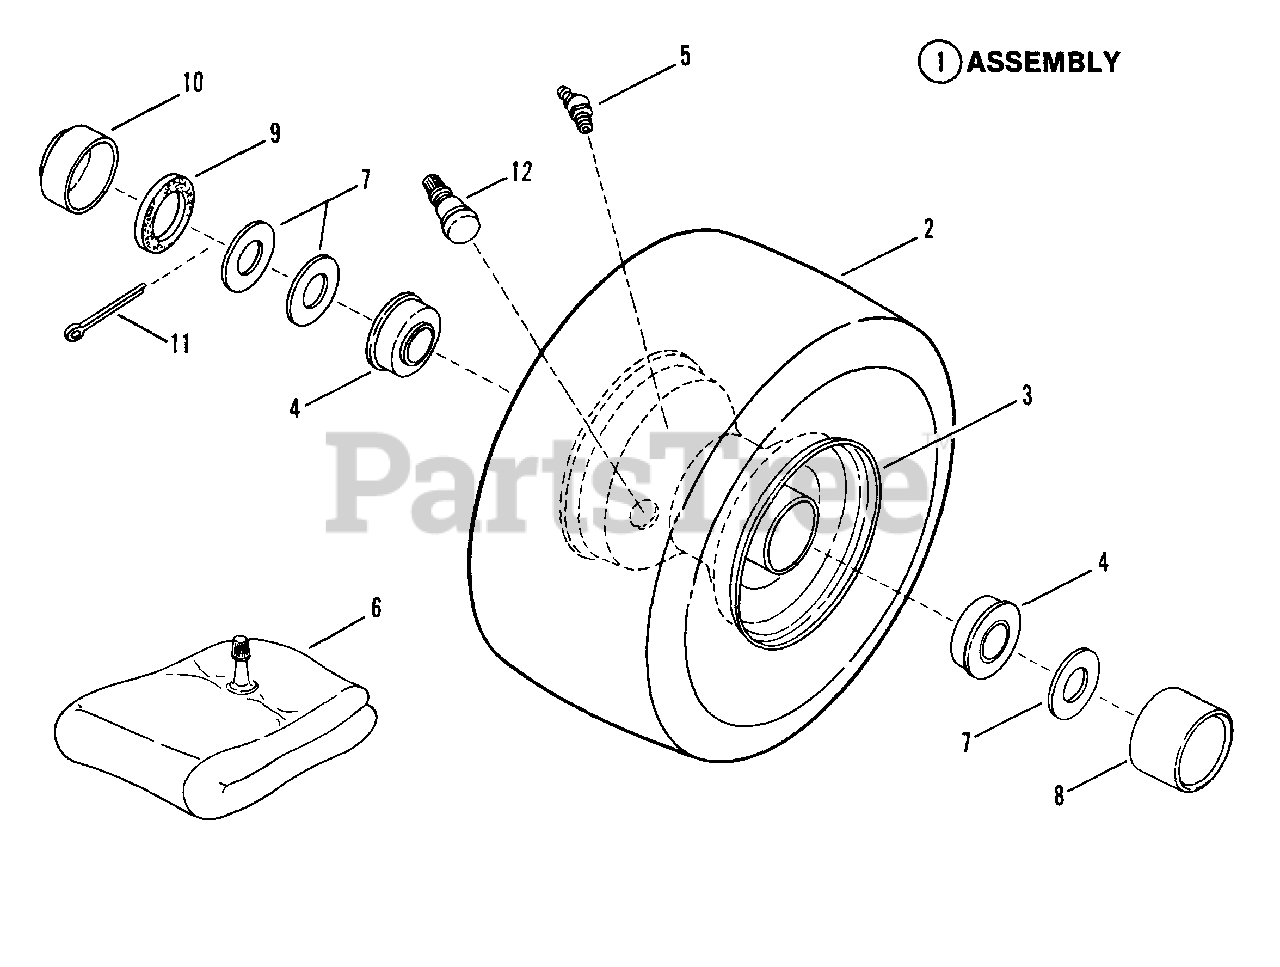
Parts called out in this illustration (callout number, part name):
1	ASSEMBLY, Front Tire & Rim
2	TIRE, 4.10/3.50 x 4
3	RIM (For 4.10/3.50 x 4 Tire)
4	BEARING, Ball
5	FITTING, Lube
6	TUBE, Inner (For 4 10/3.50 x 4 Tire)
7	WASHER
8	HUB-CAP
9	SEAL, Felt
10	CAP, Dust
11	COTTER-PIN
12	VALVE, Air (Snap-In)
